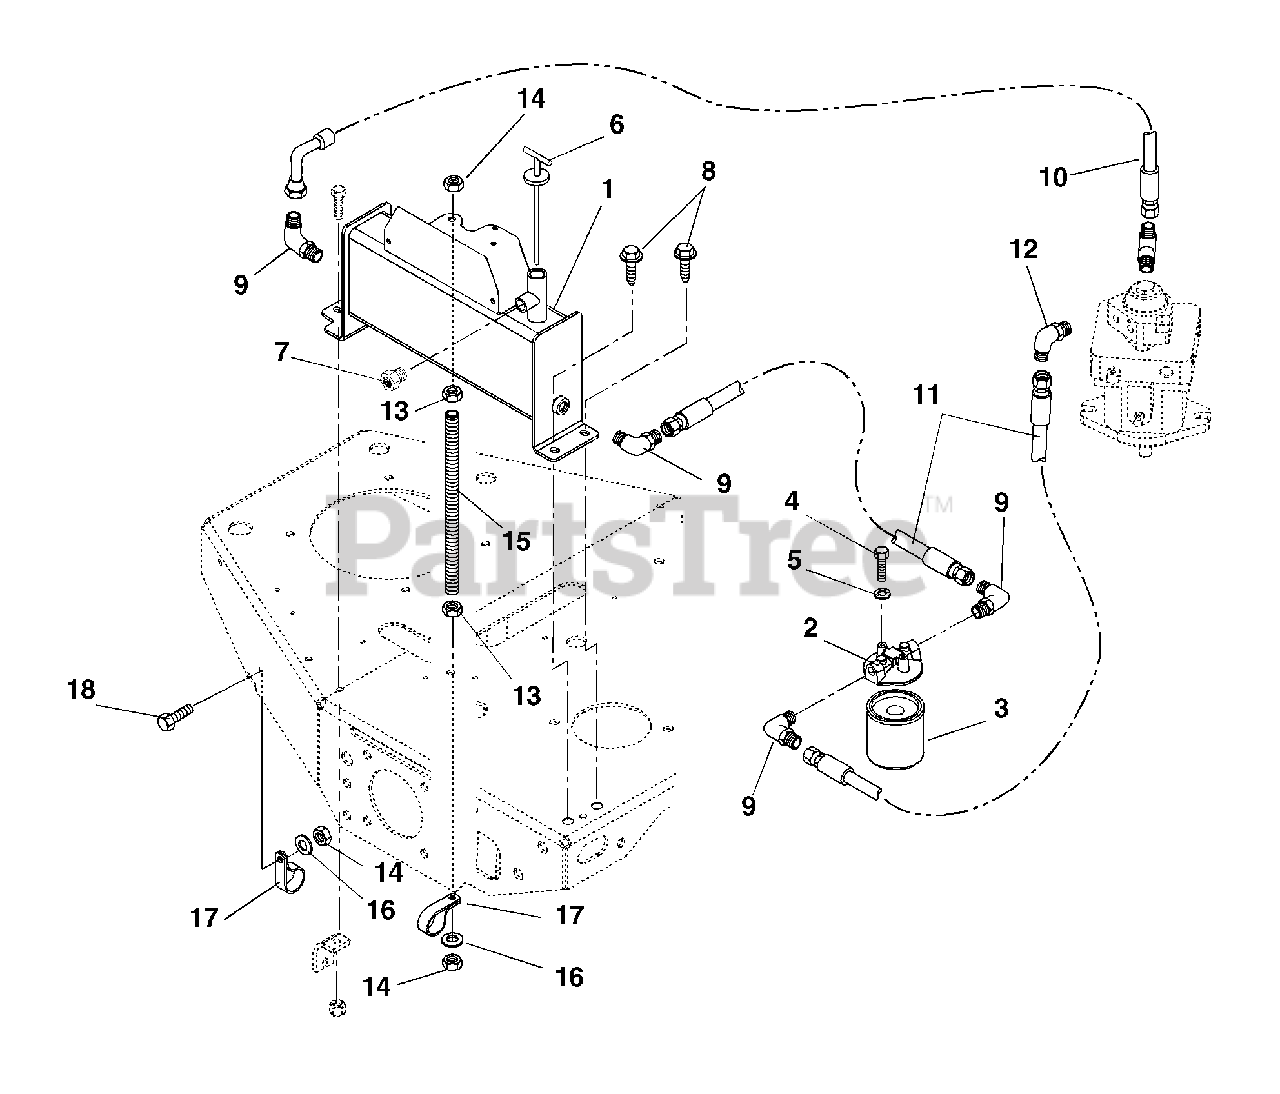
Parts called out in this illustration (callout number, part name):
1	Weldment, Hydraulic Tank
2	Head, Filter
3	Filter, Oil
4	Bolt-Hex .25-20 x .50 Grade 5
5	Washer-Locking .25 x .062 Regular
6	Dipstick, Hydraulic Tank
7	Plug, Breather .38"
8	Screw-Tapping .38-16 x .75 Hex Washer Head
9	Fitting, Hydraulic
10	Hose, Hydraulic
11	Hose, Hydraulic
12	Fitting, Hydraulic Elbow
13	Nut-Hex .38-16
14	Nut-Locking-Nylon .38-16
15	Rod, Extension
16	Washer-Flat-Steel .406 x .812 x .065
17	Clamp, Nylon
18	Bolt-Hex .38-16 x 1.00 Grade 5
